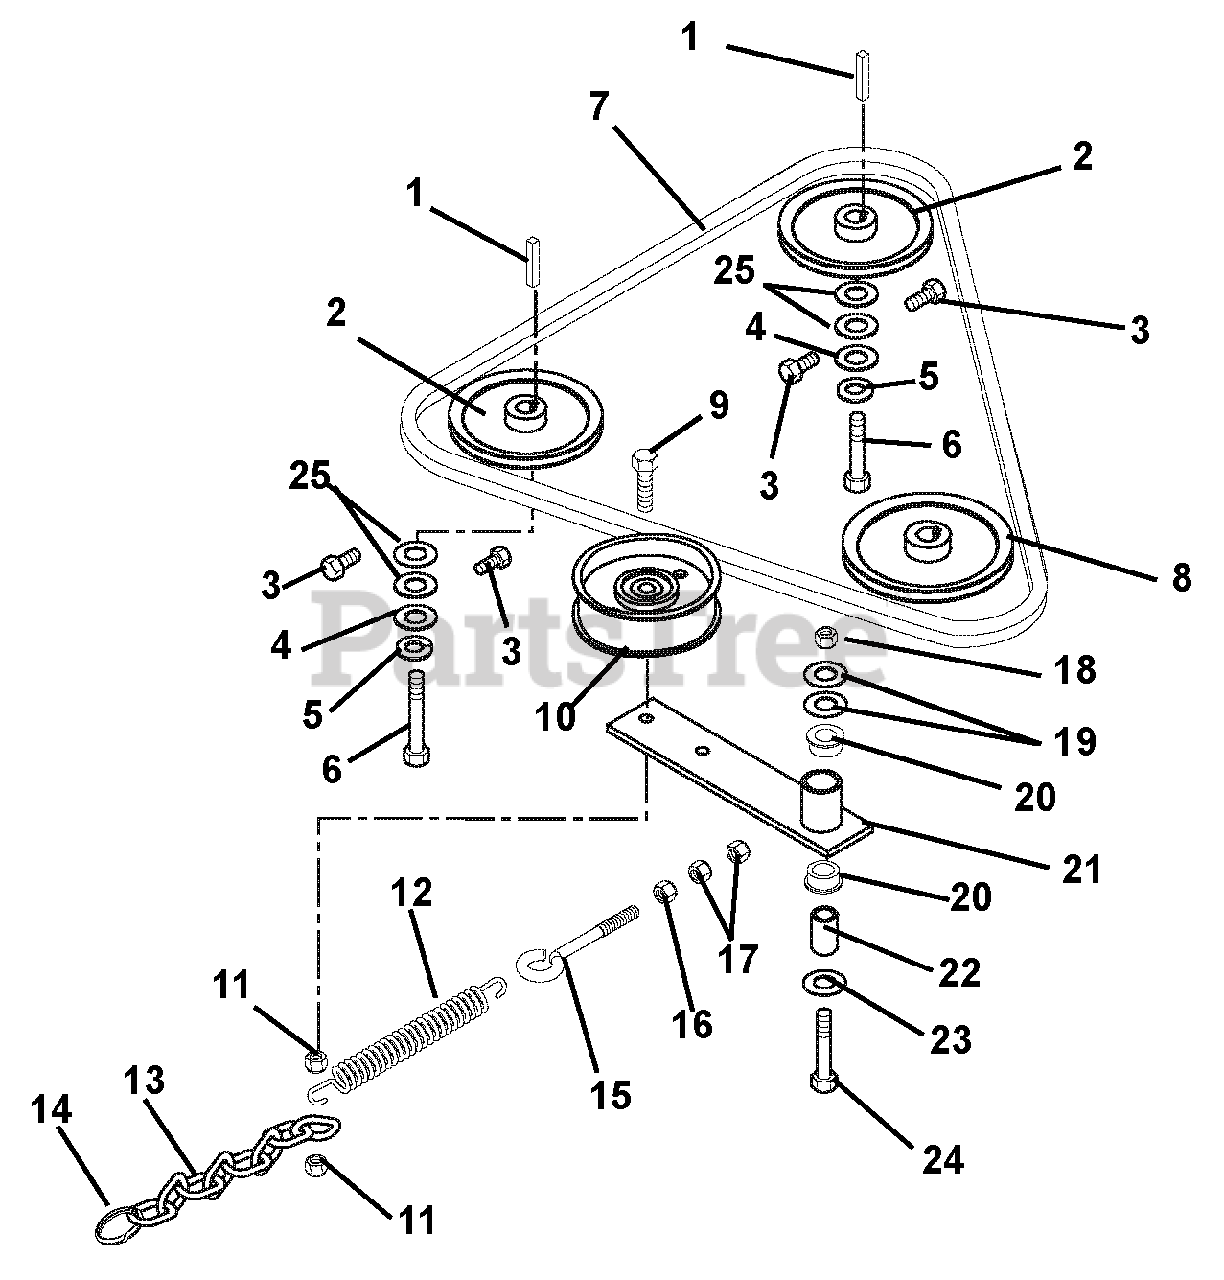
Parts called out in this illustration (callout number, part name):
1	Key, Straight 5MM x 25MM x 5MM
2	Sheave 4.0 x .199
3	Bolt, Hex .25-20 x .50 Grade 5
4	Washer, Flat-Steel .281 x 1.25 x .048
5	Washer, Locking .25 x .062 Regular
6	Bolt, Hex M6 x 1.0 x 12
7	Belt, Hydro Ground Drive
8	Sheave (988105, 120, 126, 127)
9	Bolt, Hex .38-16 x 2.00 Grade 5
10	Idler, Pulley Flat 3.25 x .625
11	Nut, Locking-Jam-Center .375-16
12	Spring, Extension
13	Chain, Link
14	Ring, Split .1 x 2
15	Bolt, Eye .375-16 x 2.50
16	Nut, Hex .38-16
17	Nut, Locking-Nylon .38-16
18	Nut, Locking-Nylon .50-13
19	Washer, Flat-Steel .531 x 1.06 x .095
20	Bushing, Flange Nylon .762 x 1.00 x .58 x 1.48
21	Weldment, Ground Drive Idler
22	Bushing, Spacer .56 x .745 x 2.04 Steel
23	Washer, Flat-Steel .531 x 1.06 x .095
24	Bolt, Hex .50-13 x 3.25 Grade 5
25	Washer, Flat-Steel .656 x 1.31 x .095 (108, 123, 124, 125)
